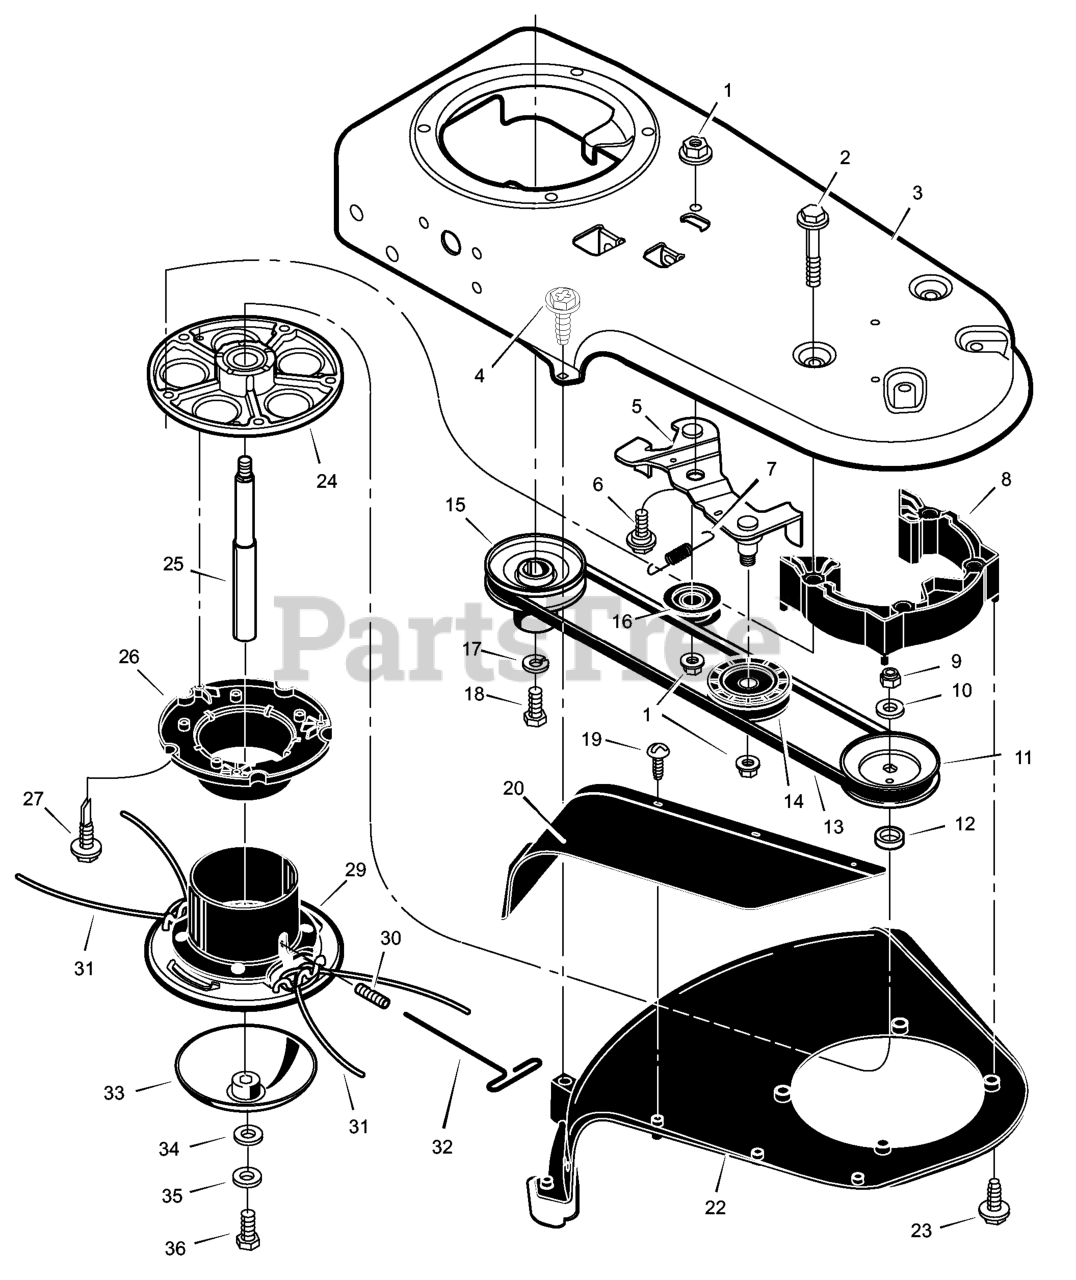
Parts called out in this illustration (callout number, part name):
1	Nut
3	Frame, Trimmer
5	Bracket, Idler Assembly
7	Spring, Extension
8	Spacer Assembly, Jackshaft
9	Nut
10	Washer, Flat
11	Pulley, Cutting Head
12	Spacer, Upper Pulley
13	Belt, Trimmer
14	PULLEY, IDLER, V, 1.88
15	Pulley, Engine
16	Pulley, Idler
17	Lockwasher
20	Flap, Depris
22	Shield, Trimmer
24	Housing, Jackshaft
25	Shaft, Cutting Head
26	Wrap, Weed
29	Assembly, Cutter Head & Wrap
31	Line, Trimmer 0.155 X 21.25
32	Wrench, T-Handle
33	Guide Assembly, Height
34	Washer, Flat
35	Lockwasher
